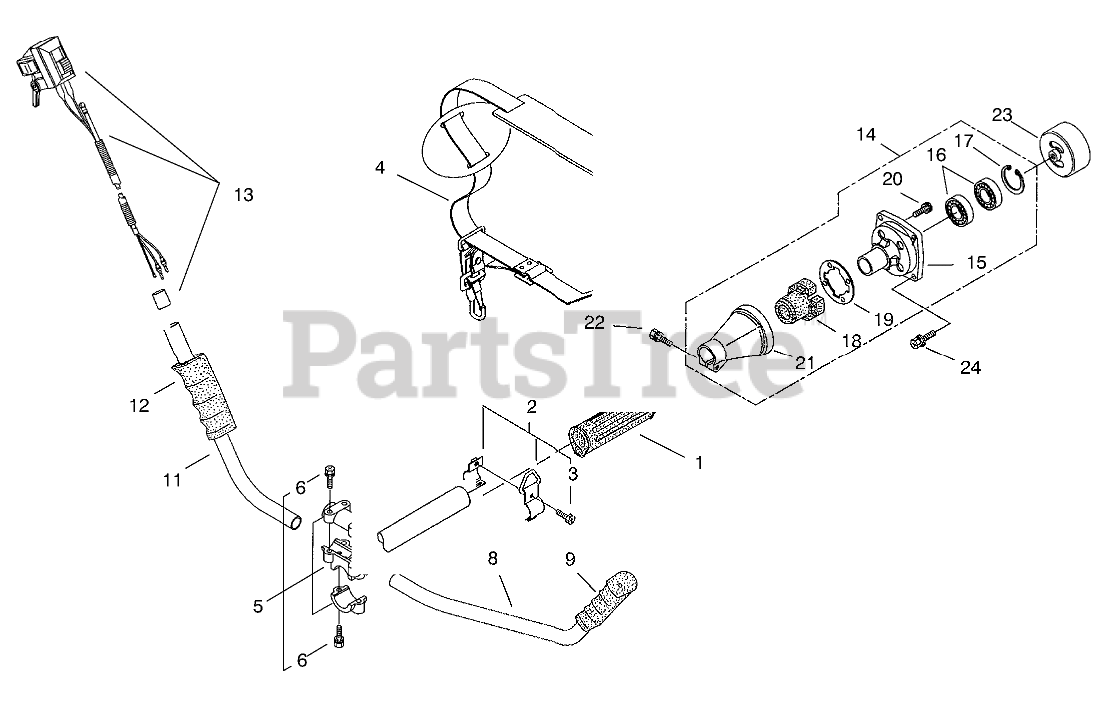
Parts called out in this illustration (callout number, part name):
1	GRIP - SHAFT
2	Hanging Bracket Assembly (Incl. Ref. #3)
4	ASM - SHOULDER STRAP
5	Bracket Assembly (Incl. Ref. #6)
8	HANDLE
9	GRIP - HANDLE
11	HANDLE
12	GRIP - HANDLE
13	TRIGGER - THROTTLE
14	Clutch Case Assembly (Incl. Ref. #16-24)
15	CASE - BEARING
16	BEARING
17	RING - SNAP
18	BUFFER
19	WASHER
20	SCREW
21	ADAPTER-DRIVESHAFT TUBE
23	DRUM - CLUTCH
